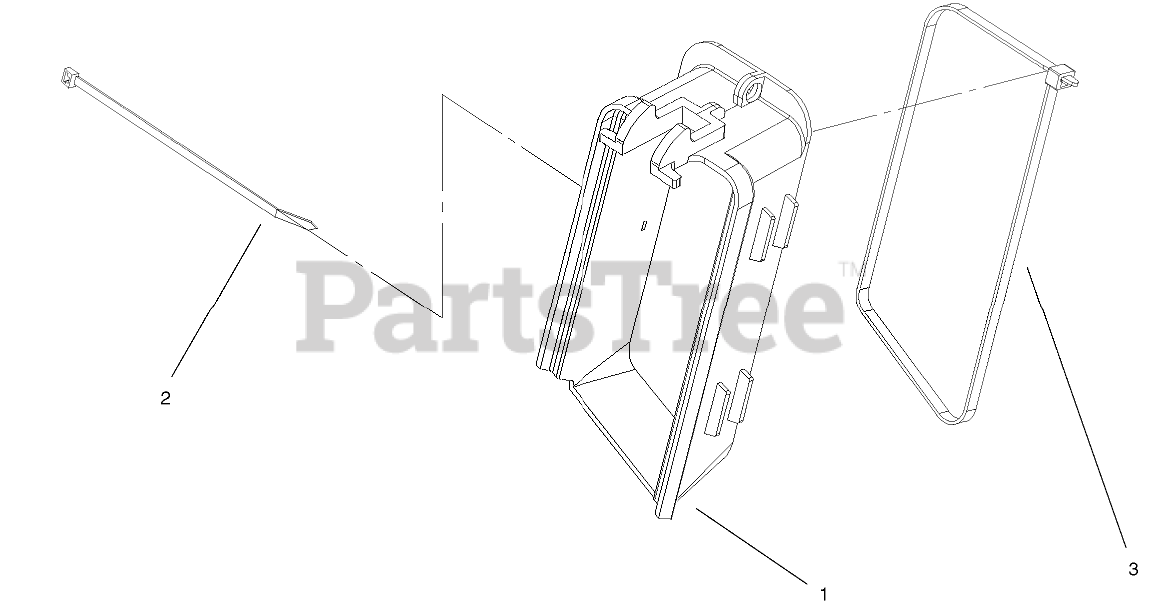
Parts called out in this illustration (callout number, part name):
1	Chute-Bag,Inlet
2	TIE-CABLE
3	STRAP-TIE
